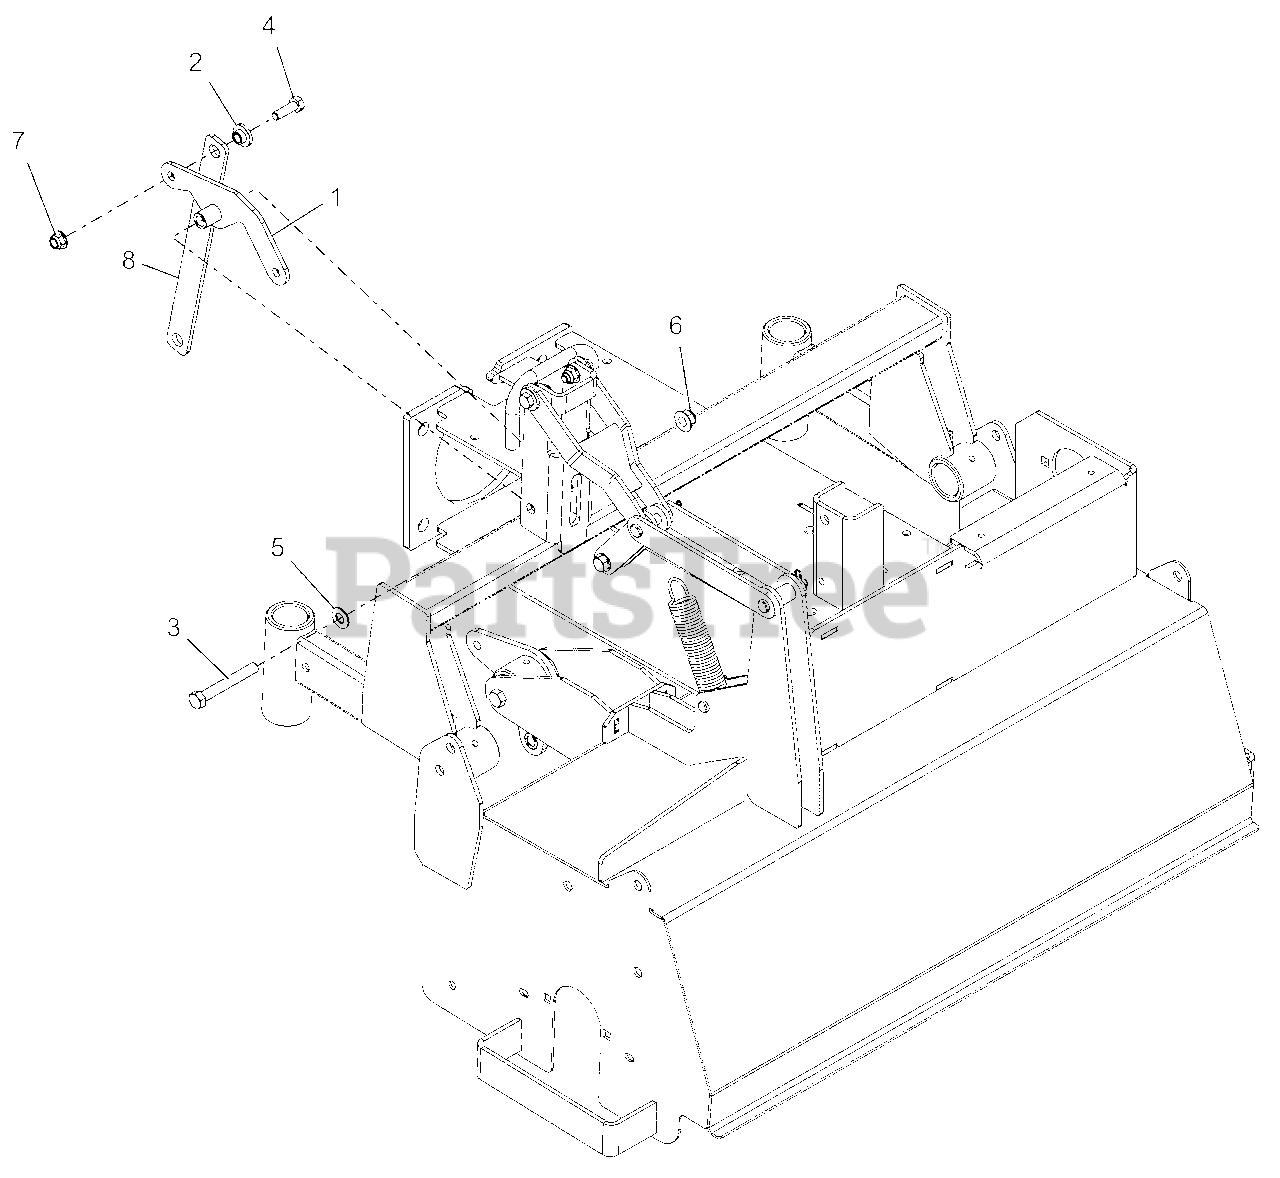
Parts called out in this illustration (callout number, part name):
1	WLDMT, LIFT LINK
2	BSHG-FLG .32X.500X.344X.880
3	BLT, HEX .38-16X2.75 G5 ZCC
4	BLT,HEX .31-18X1.00 G5 ZCC
5	WSHR,FLT .406X.812X.065 ZCC
6	NUT,NYL-FLG .38-16 GF ZCC
7	NUT,NYL-FLG .31-18 GF ZCC
8	BRKT, HANDLE MNT
